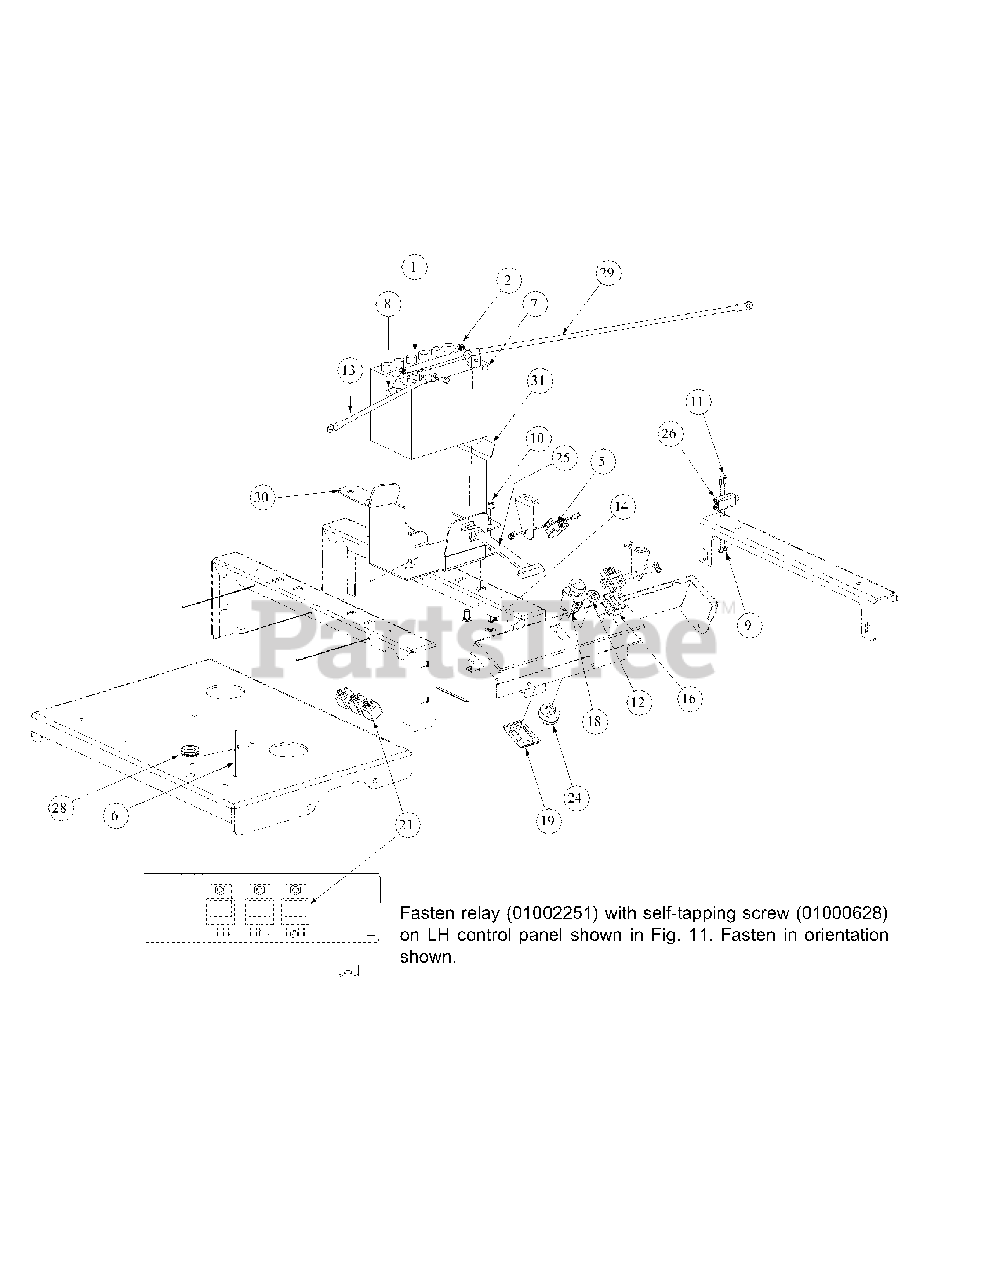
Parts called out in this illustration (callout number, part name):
1	Battery, 12V 225CCA 30 Min
2	Lock Nut, 1/4-20
5	Switch, Safety, NO/NC
6	Tie, Cable, 3/16 x .05 x 7.4"
7	Screw, Hex, Cap, 1/4-20 x .75
8	Boot, 1" OD Rubber Battery-PST, Red
9	Lock Nut, Nylon Insert, #10-32
10	Nut, Hex, Flange Lock, 3/8-16
11	Screw, Phillips Head, Machine, 10-32 x 5/8
12	Nut, W/Cap, 5/8-32 Ignition
13	Cable, Battery, Red, 36"
14	Carriage Bolt, 3/8-16 x .75 LG.
16	Meter, Hour
18	Switch, Electric, PTO
19	Bracket, PTO Switch Retainer
21	Relay, 12V 40A
24	Switch, Ignition, 6 Pin
24	Key, Ignition
25	Strap, Battery
26	Switch, Plunger, NO/NO
28	Grommet, .75 ID
29	Cable, Battery Red,28"
30	Mount Bracket, Battery
31	Mount Bracket, Battery
